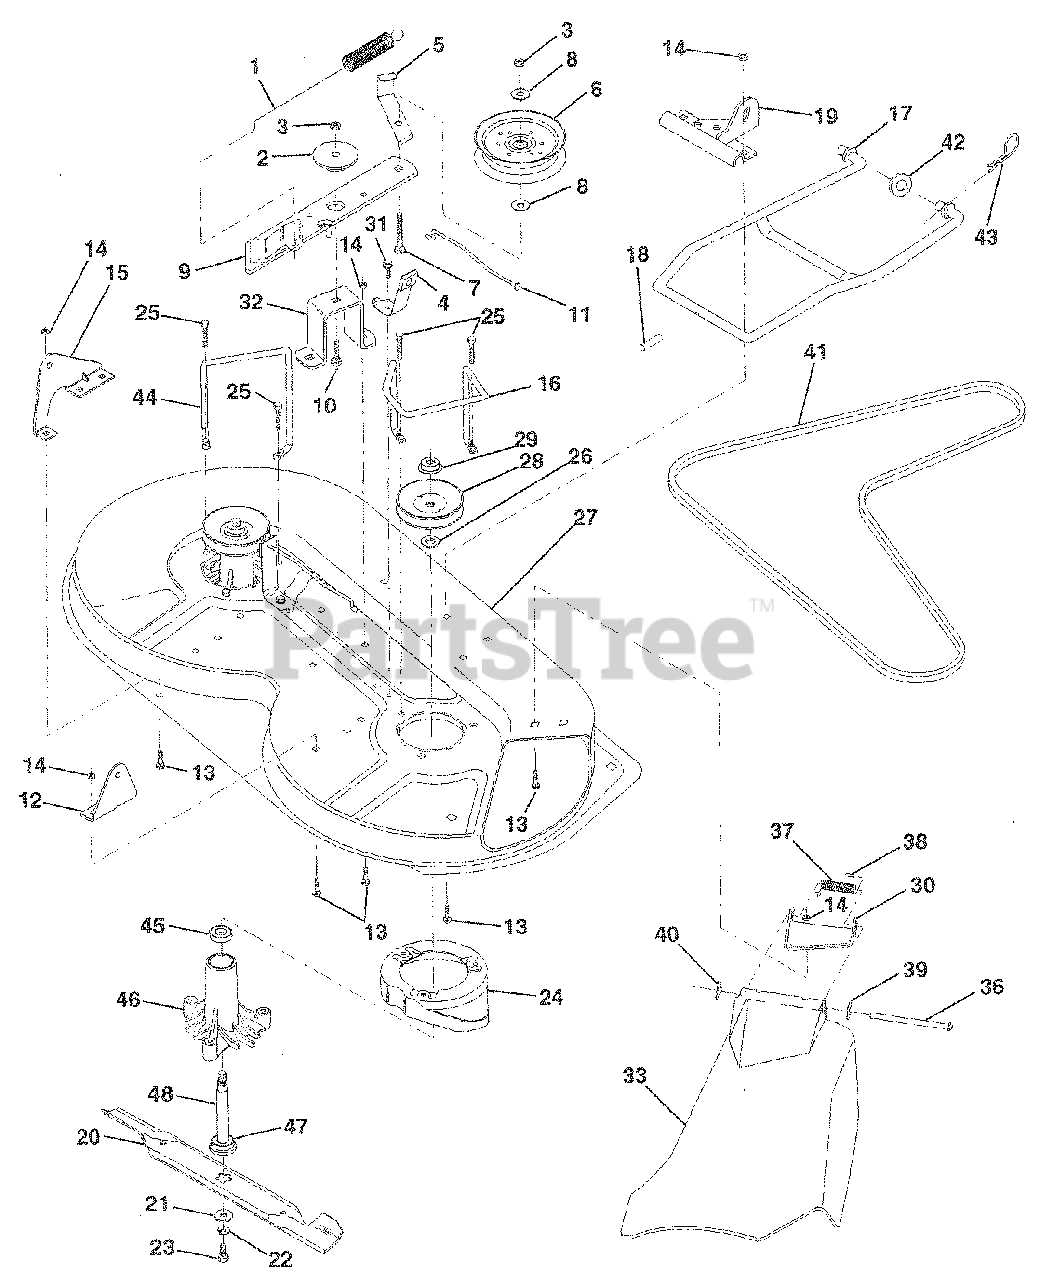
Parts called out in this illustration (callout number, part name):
1	Spring, Mower Clutch
2	Spacer, Retainer
3	Nut, Crownlock
4	Brake Asm.
5	Guide, Beit Idler
6	Pulley, Flat Idler
7	Bolt, Carr. 3/8-16 x 1-3/4 Gr. 5
8	Washer 13/21 x 7/8 x 10 Ga.
9	Arm Asm., Idler Mower
10	Bolt, Carriage 3/8-16 x 1
11	Rod, Brake
12	Bracket, Lift R. H. Rear
13	Bolt, Carnage 5/16-18x5/8
14	Nut, Crownlock 5/16-18
15	Bracket, Lift L. H. Rear
16	Keeper, R. H.
17	Link, Asm. Mower Stabilizer
18	Pin, Drive
19	Bracket, Asm. Front
20	Blade
21	Washer, Hard
22	Washer, Lock 3/8
23	Bolt 3/8-24 x 1-1/4 Gr. 8
24	Stripper
25	Bolt 5/16-18x1-1/4
26	Washer .150 Thk.
27	Deck Assembly
28	Pulley, Mandrel
29	Nut, Centerlock 9/16
30	Bracket, Asm. Deflector
31	Screw, Hex Wsh. Thdrol. 5/16-18 x 1/2
32	Arm, Support Idler Mower
33	Deflector
36	Rod, Hinge
37	Spring, Torsion Deflector
38	Cap, Sleeve
39	Washer 11/32 x 5/8 x 16 Ga.
42	Washer 11/32 x 5/8 16 Ga.
43	Retainer, Spring
44	Keeper, L. H.
46	Housing Mandrel Vented
48	Shaft, Mandrel
